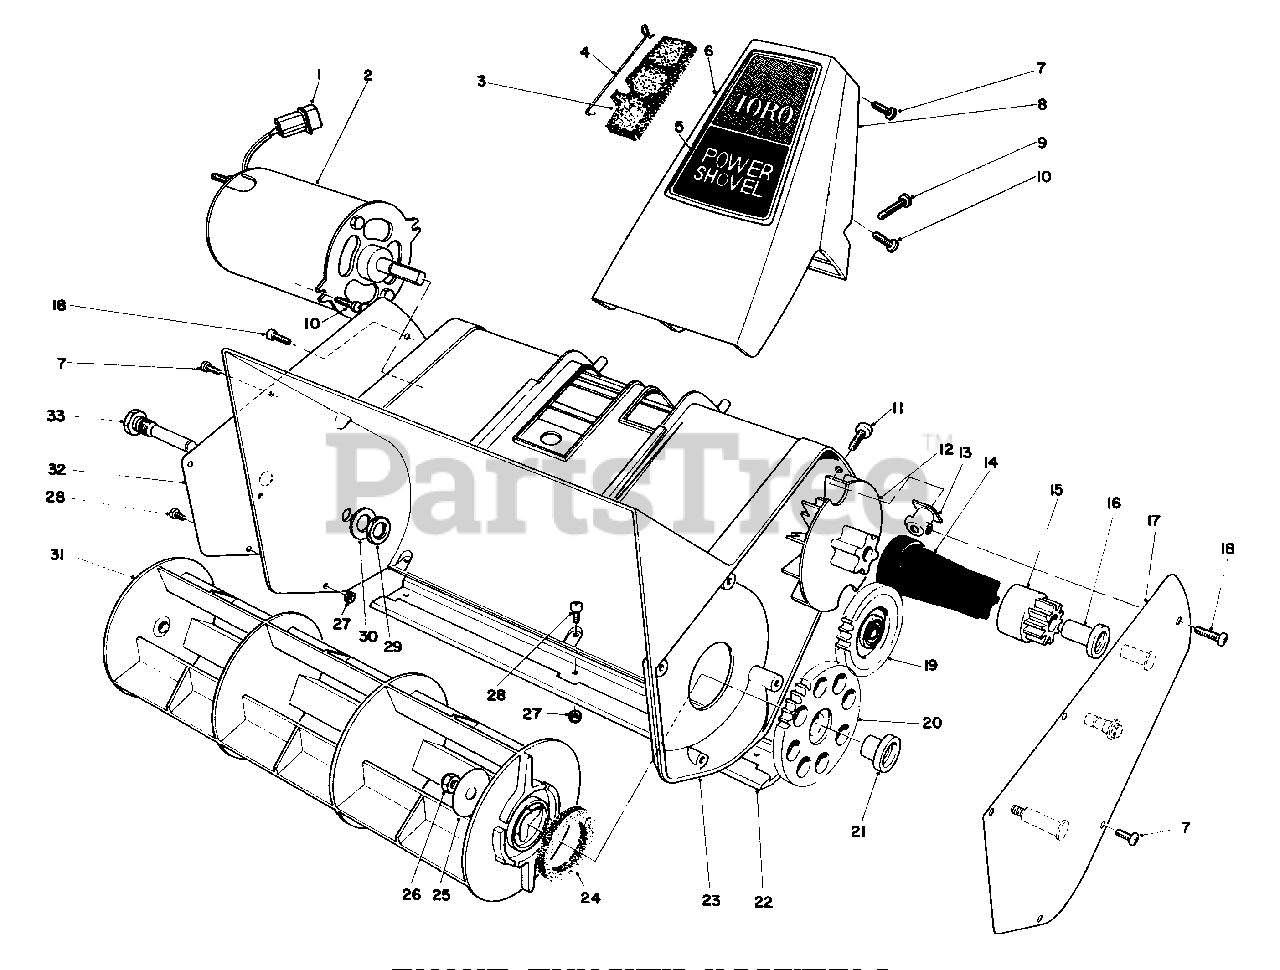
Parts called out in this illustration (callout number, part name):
1	Pin Housing
2	Motor
3	Filter-Foam
4	Retainer-Filters
5	Decal-Handle Support
6	Handle Support-Front
7	Screw-Pan Head
8	Handle Support-Back
9	Screw-Pan Head
10	Screw-Pan Head
11	Screw-Phillips Truss
13	Block-Mounting
14	Coupling-Drive
15	Drive Gear (Incl. Ref. #16)
16	Bushing-Drive Gear
17	Gear Carrier
18	Screw-Pan Head
19	Idler Gear Assembly
20	Rotor Gear Assembly (Incl. Ref. #21)
21	Bushing-Rotor
22	Scraper
23	Housing
24	Washer-Felt
25	Washer-Rotor
26	Locknut-Thin
27	Locknut-Thin
28	Screw-Pan Head
29	Nut-Lock
30	Flat Washer
32	Cover, Right Side
33	Pin-Rotor
